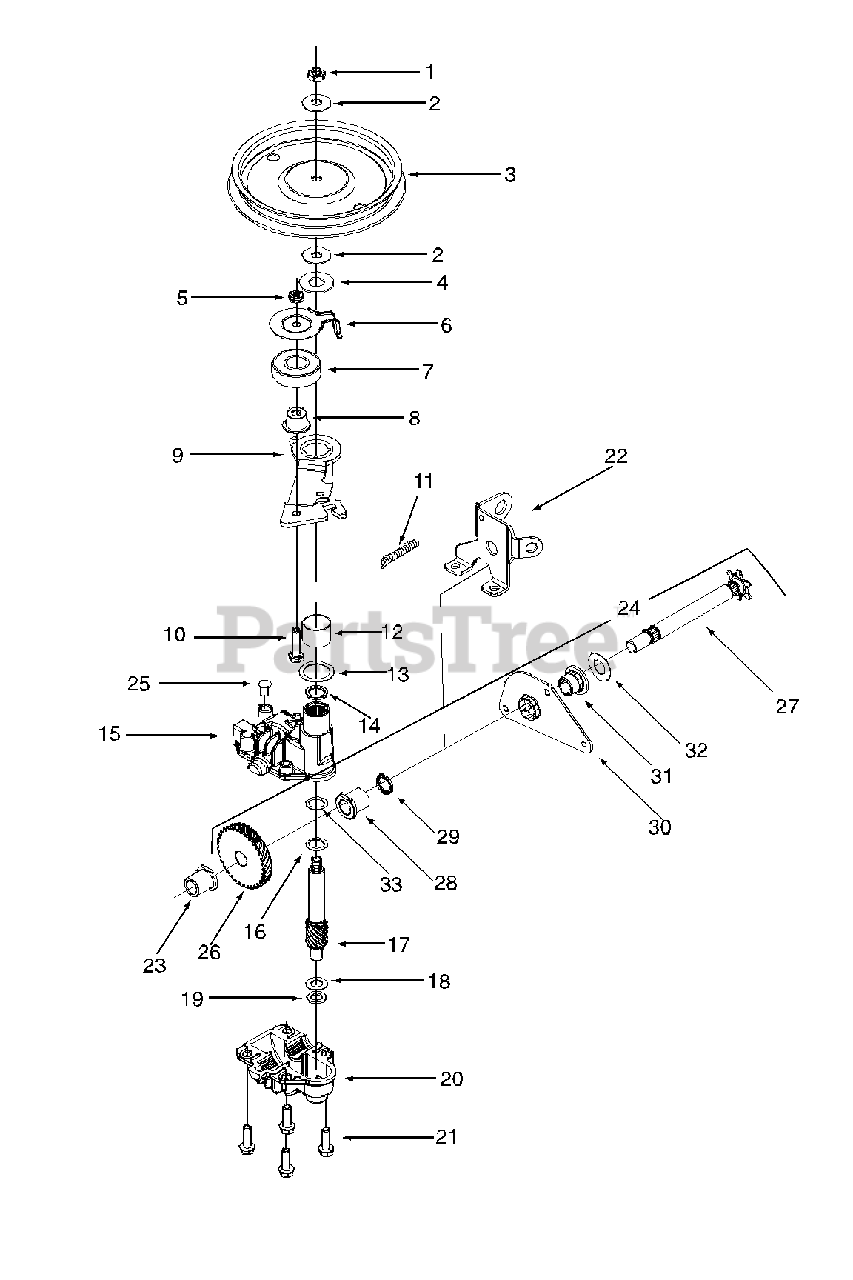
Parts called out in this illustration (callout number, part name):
1	Hx. Jam Nut 5/16-24
2	Bell Wash. .325 x .930 x .045
4	Fl. Wash. .510 x 1.120 x .060
5	Hx. Jam Nut 1/4-28
6	Belt Keeper
7	Bearing
8	Flange Spacer
9	Idler Bracket Ass'y.
10	Hx. Cap Scr. 1/4-28 x 1.00 Gr. 5
11	Torsion Spring
12	Bearing Sleeve
13	Fl. Wash. .885 x 1.145 x.030
14	Oil Seal
15	Upper Housing Ass'y.
16	Fl. Wash. .504 x .700 x .030
17	Pinion Shaft 10 T.
18	Thr. Wash. 3/8 x .70 x .030
19	Thr. Wash. .388 x .625 x .062
20	Lower Housing Ass'y.
21	Hx. Scr. 1/2-20 x .75
24	Shaft Ass'y.
26	Gear 34 T.
27	Output Shaft 6 T.
28	Flange Bearing
29	Oil Seal
30	Pivot Bracket
31	Flange Bearing
32	Wash. Fl. .508 I.D. x 1.00 O.D. x .020
33	Thrust Bearing
